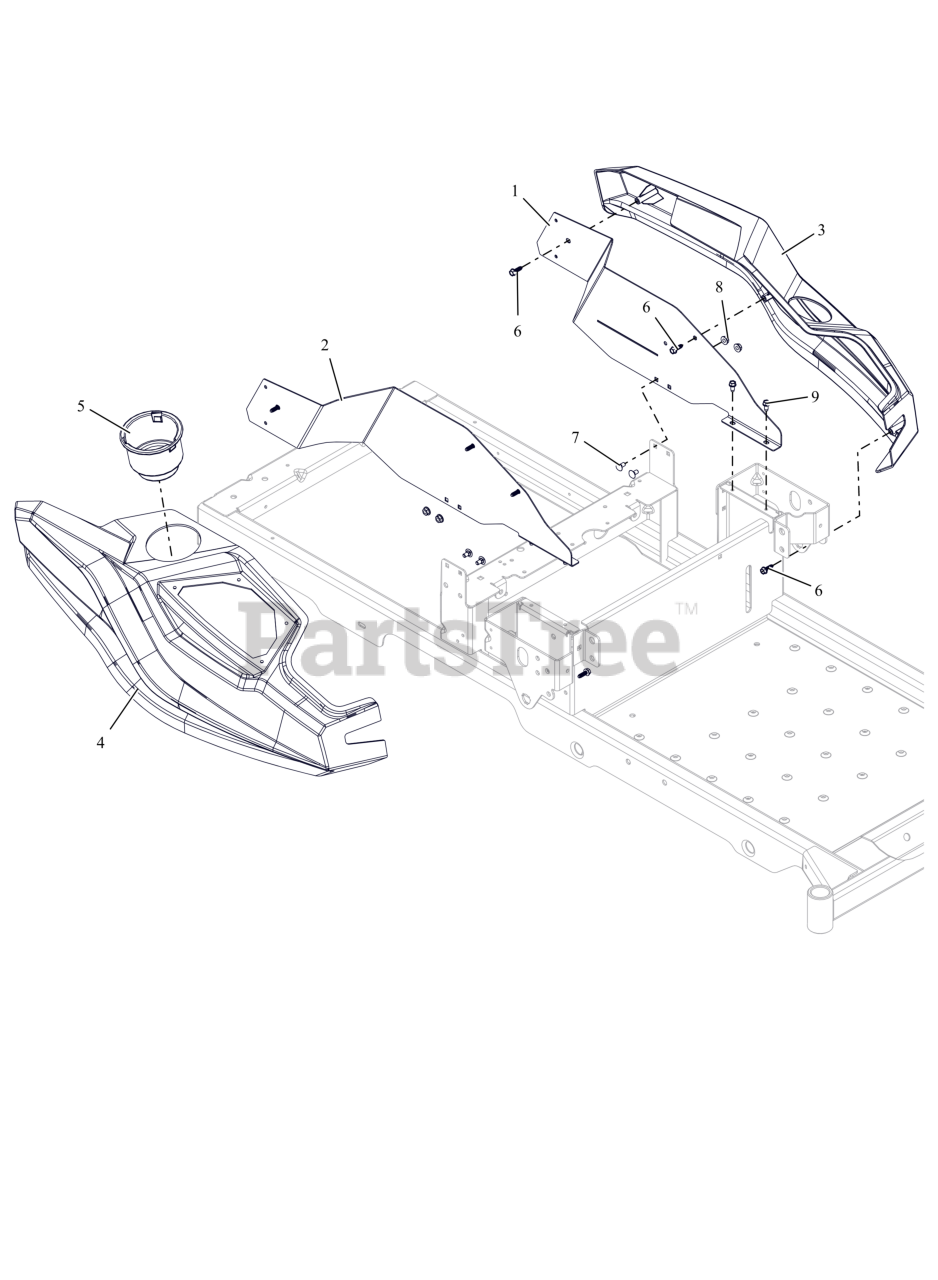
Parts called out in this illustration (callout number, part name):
1	BRKT- FENDER MOUNTING LH
2	BRKT- FENDER MOUNTING RH
3	KIT-FENDER WITH DECAL
4	FENDER, RH
5	CUPHOLDER, SNAP-IN 3.75OD
6	SCR, PLASTITE-HWH 0.25 X 0.75 ZC120
7	BLT, RHSN .25-20X.500 G5 ZCC
8	NUT-LK-CTR-FLG .25-20 ZC120
9	SCR-TAP .25-20X.50 HWH ZCC
